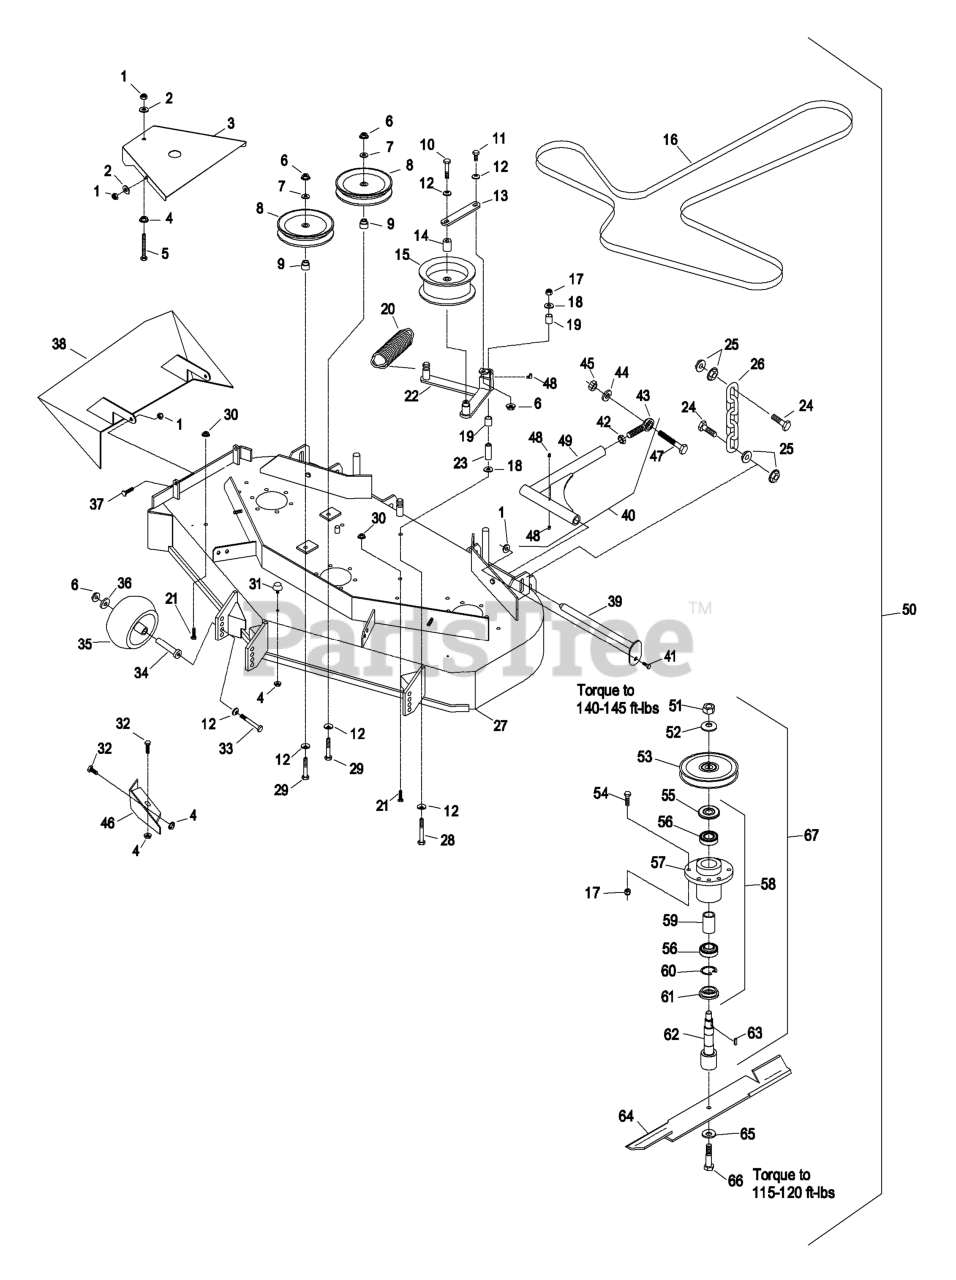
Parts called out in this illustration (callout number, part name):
1	NUT-LOCK, NI
2	WASHER-FLAT
3	SHIELD,BELT
5	BOLT,TAP HH
6	NUT-HHF, WHIZ
7	WASHER-FLAT
8	PULLEY-IDLER
9	BUSHING-IDLER
10	SCREW-HH
11	SCREW-HH
12	WASHER-BELLEVILLE
16	BELT,DECK DRIVE
17	NUT-LOCK, NI
18	WASHER-HARDENED
19	SLEEVE-BEARING
21	SCREW-HH
23	BUSHING-PIVOT, IDLER
24	SCREW-CAP, HH
26	CHAIN-LIFT, DECK
27	ASM,DECK W/DECALS LHP48 S
28	SCREW-HH
29	SCREW-HH
31	BUMPER-RUBBER
32	SCREW-HH
33	SCREW-HH
34	BUSHING-ROLLER
35	ROLLER-SCALP, ANTI
37	SCREW-HH
38	WLD,CHUTE 48
39	PIN-STRUT
40	STRUT ASM
41	SCREW-HH
42	NUT-HEX
43	BALLJOINT-SPHERICAL
44	WASHER-LOCK
45	NUT-HEX
48	FITTING-GREASE
50	Deck Complete Service(44")
53	SHEAVE,W/HUB
54	SCREW-HH
55	GUARD-BEARING, TOP
56	BEARING-JACKSHAFT
59	SPACER-BEARING
60	RING-SNAP
61	SPACER-GUARD, BOTTOM
62	SPINDLE,LHP
63	KEY-RECTANGLE
65	WASHER-BLADE BOLT, HEAVY
66	SCREW-CAP
